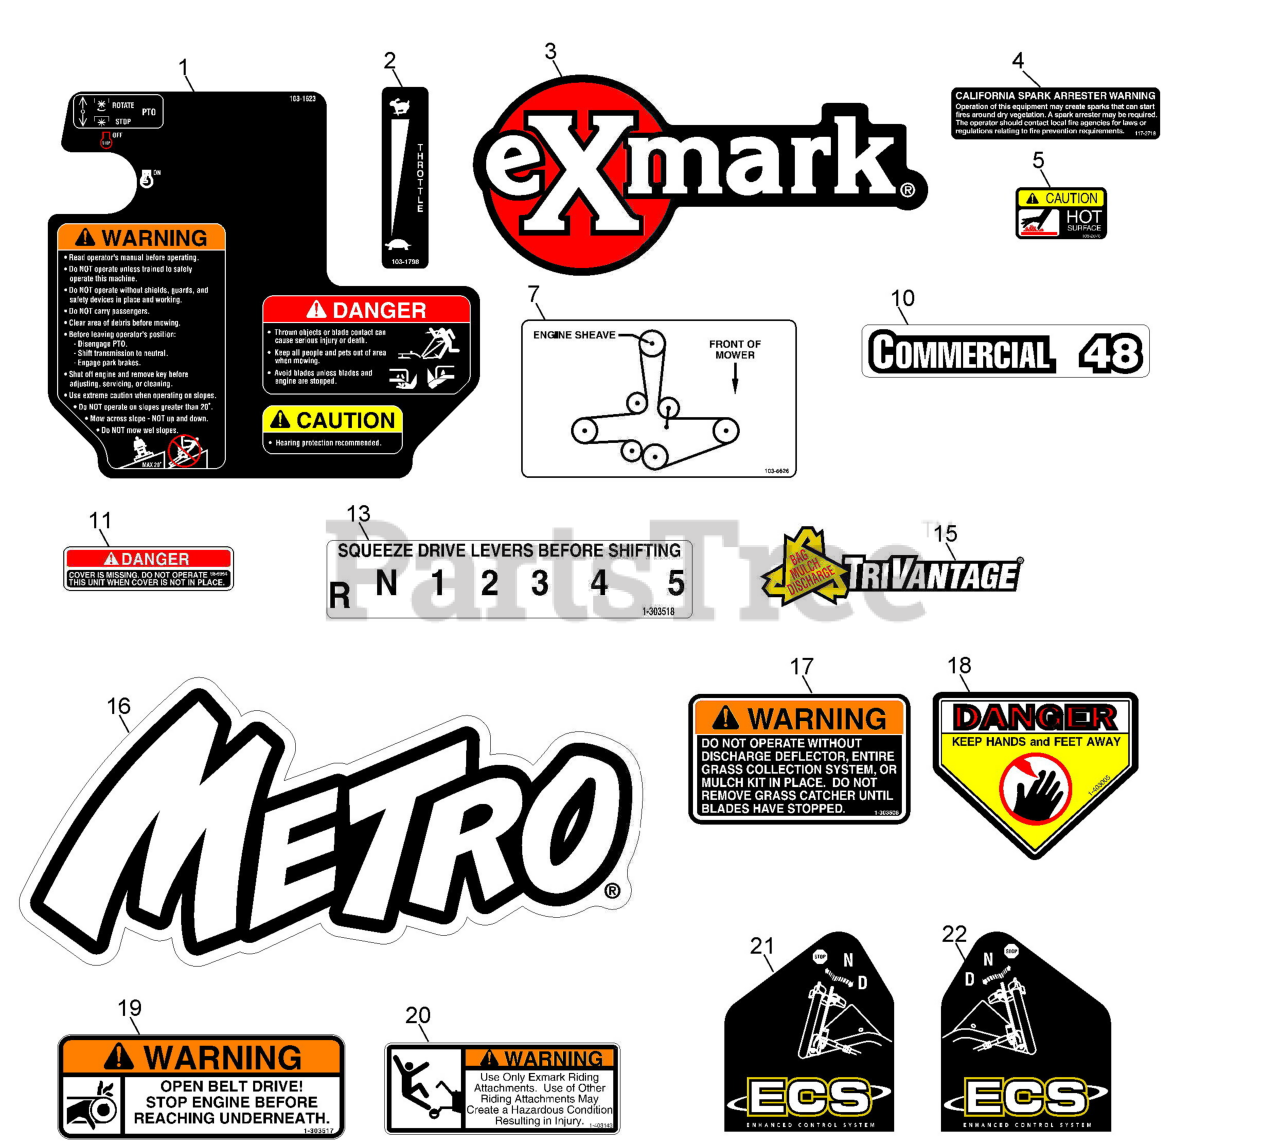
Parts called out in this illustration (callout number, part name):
1	DECAL,METRO ECS CONSOLE
2	DECAL,THROTTLE ONLY
3	DECAL,EXMARK LOGO
4	DECAL-ARRESTER, SPARK
5	DECAL-CAUTION
7	DECAL,BELT ROUTING
10	DECAL,COMMERCIAL 48
11	DECAL-COVER, MISSING
13	DECAL,SHIFTER
16	DECAL,METRO MODEL
17	DECAL-WARNING, DISCHARGE
18	DECAL-DANGER
19	DECAL,BELT DRIVE
20	DECAL,SULKY WARNING
21	DECAL,RH ECS INSTRUCTION
22	DECAL,LH ECS INSTRUCTION
